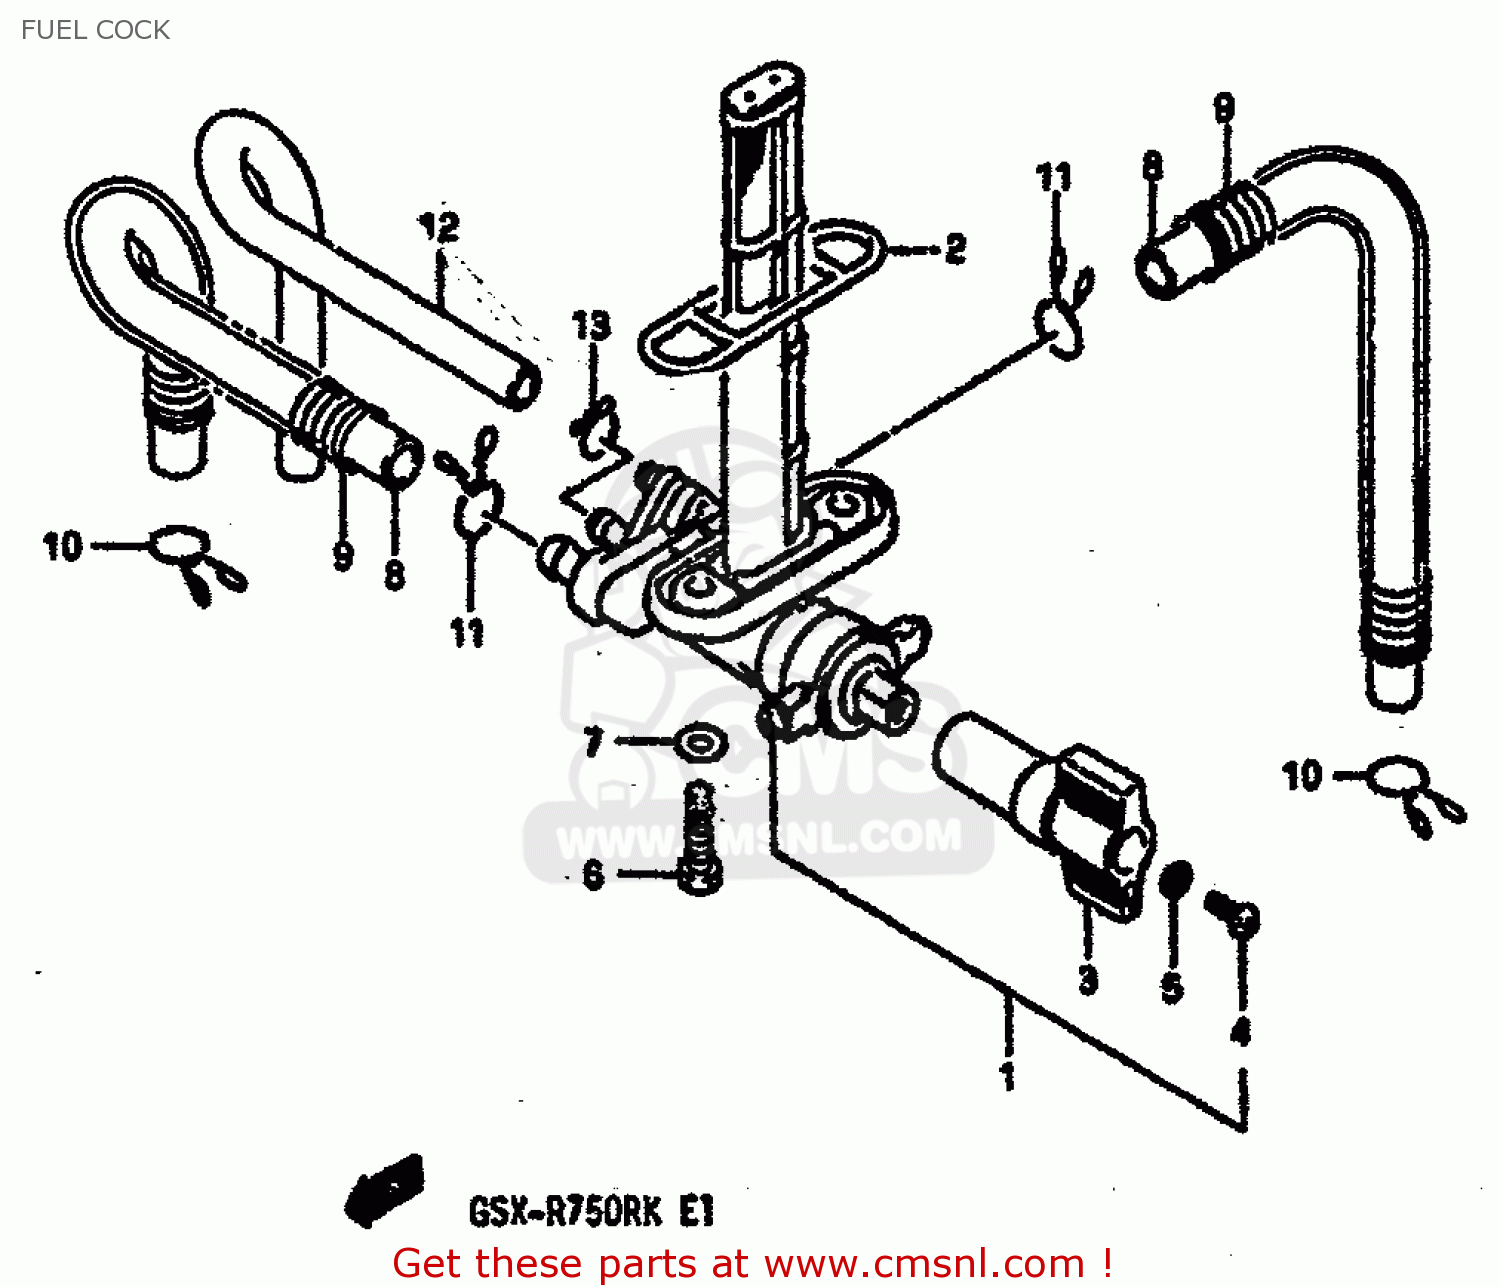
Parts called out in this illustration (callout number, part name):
1	COCK ASSEMBLY,FUEL
2	O RING,FUEL TANK JOINT
3	LEVER,FUEL COCK
4	SCREW
5	LOCK WASHER
6	BOLT(6X20)
7	GASKET(6.4X11.5X0.8) (NAS)
8	HOSE
9	SPRING
10	CLIP
11	CLIP
12	HOSE
13	CLIP
